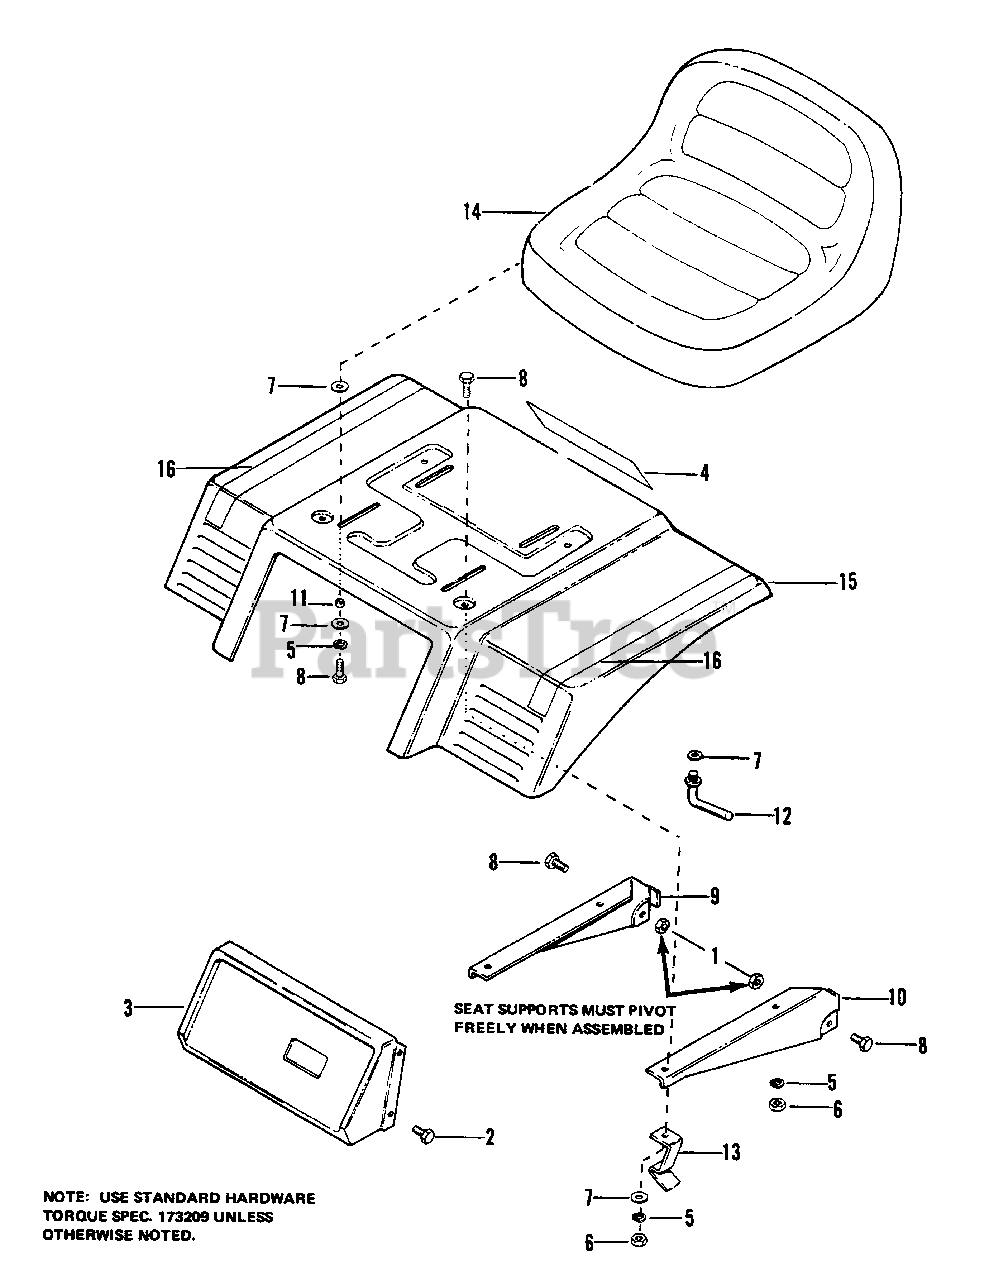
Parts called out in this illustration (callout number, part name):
1	LOCKNUT, Hex, 5/16-18
2	SCREW, Hex, Washer Hd., 1/4-20 x 1/2
3	PANEL, Shift
4	DECAL, Simplicity
5	LOCKWASHER, Spring 5/16
6	NUT, Hex 5/16-18
7	WASHER, Plain 5/16
8	CAPSCREW, Hex Hd., 5/16-18 x 3/4
9	SUPPORT, Rh, Seat
10	SUPPORT, Lh, Seat
12	SCREW, Hand
13	LATCH, Spring
15	DECK, Seat
16	DECAL, Seat Deck
